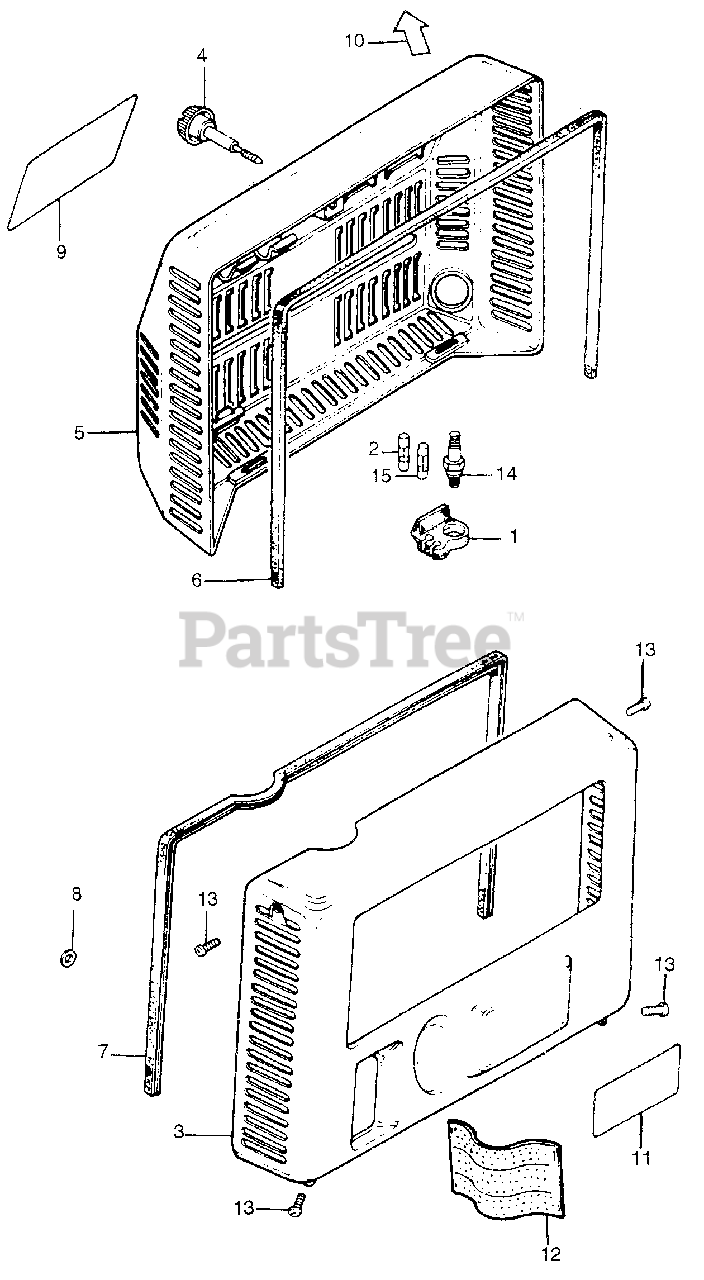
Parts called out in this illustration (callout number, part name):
1	HOLDER, SPARE PLUG
2	FUSE ASSY., SPARE
3	COVER, FR. *NH31* (MCKINLEY WHITE)
4	LATCH, COVER
5	COVER, RR. *NH31* (MCKINLEY WHITE) (NOT AVAILABLE)
6	RUBBER B, RIM COVER (NOT AVAILABLE)
7	RUBBER C, RIM COVER
8	STOPPER, LATCH
9	PLATE, NAME (NOT AVAILABLE)
10	MARK, EX. CAUTION
11	MARK, OIL CHECK (NOT AVAILABLE)
13	SCREW, PAN (5X10)
13	SCREW-WASHER (5X10)
14	SPARK PLUG (CM6) (NGK)
15	FUSE A (10A)
